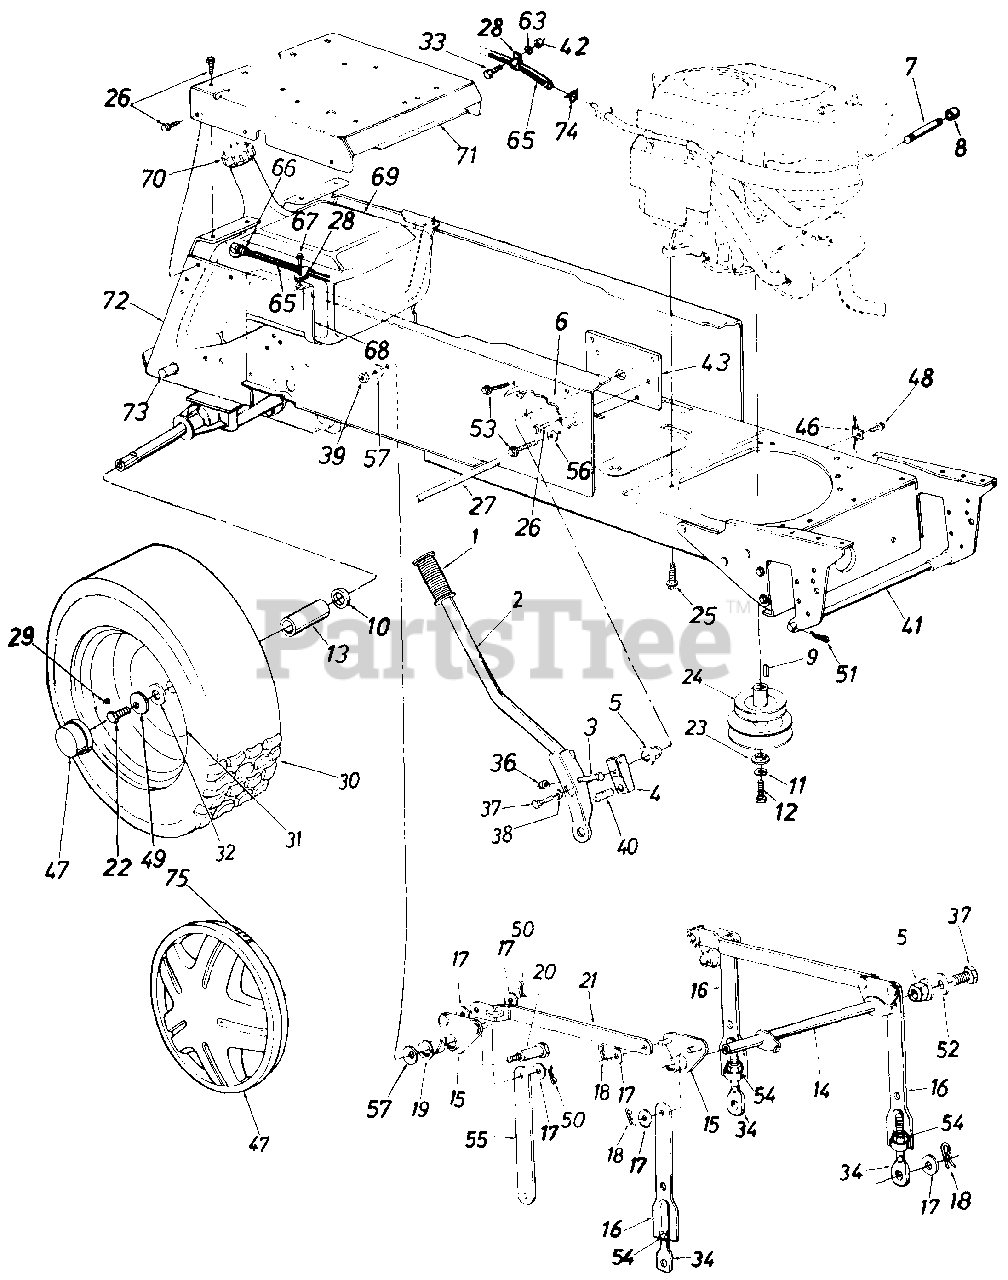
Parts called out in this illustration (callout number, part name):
1	Grip
2	Lift Handle Ass'y.
3	Hex Bolt 5/16-18 x 1.5" Lg.
4	Lift Shaft Drive
5	Plastic Hex Brg. 5/8" I.D.
8	Pipe Cap 3/8-18 Npt.
9	Sq. Key 1/4" x 1/4" x 1.50" Lg.
10	Fl-Wash. .76" I.D. x 1.49" O.D.
11	L-Wash. 7/16" I.D.
12	Hex Scr. 7/16-20 x 1.50" Lg.
13	Sleeve .75" I.D. x 1" O.D.
14	Lift Shaft Ass'y.
15	Lift Pivot Brkt. Ass'y.
17	Fl-Wash. 1/2" I.D. x 1.00" O.D. x .090"
18	Hairpin Cotter
19	Nyliner 5/8" I.D. x .88" Lg.
20	Shld. Bolt 5/8" Dia. x .96" Lg. 3/8-16
23	Flat Wash. .44" I.D. x 1.25" O.D. x .17"
24	Two-Step Engine Pulley
25	Hex Wash. Hd. Scr. 3/8-16 x 1.25" Lg.
26	Hex Thd. Rolling Scr. 5/16-18 x .75" Lg.
27	Running Board Rod
28	Clamp
29	Air Valve
30	Rear Wheel Ass'y. Comp.
31	Rear Wheel Rim Only
32	Flat Wash. .34" I.D. x 2" O.D.
33	Hex Bolt 1/4-20 x .62" Lg.
34	Eye Bolt Adj. Link 1/2-13 Thd.
36	Hex Cent. L-Nut 5/16-18 Thd.
37	Hex Bolt 5/16-24 x .62" Lg.
38	L-Wash. 5/16" I.D.
39	Hex Top L-Nut 3/8-16 Thd.
40	Compression Spring
41	Deck Connecting Rod
42	Hex Nut 1/4-20 Thd.
47	Hub Cap
48	Hex Wash. Hd. TT-Tap Scr. 1/4-20 x .5" Lg.
49	Bell-Wash. .39" I.D.
50	Cotter Pin .09 Dia. x 1.0" Lg.
51	Int. Cotter Pin
52	Flat Wash. .34" I.D. x 1.12" O D. x .125"
53	Hex Wash. Hd. AB-Tap Scr. 5/16-24 x .5" Lg.
54	Hex Nut 1/2-13 Thd.
56	Fl-Wash. .344" I.D.
57	Bell-Wash. .4" I.D. x 1.13" O.D.
63	L-Wash. 1/4" I.D.
65	Fuel Line 46" Lg.
66	Hose Clamp
67	Hex AB-Tap Scr. 1/4 x .62" Lg.
68	Fuel Tank Strap
69	Gas Tank
70	Gas Gauge
73	Hitch Rod
74	Hose Clamp
75	Spring Clip
